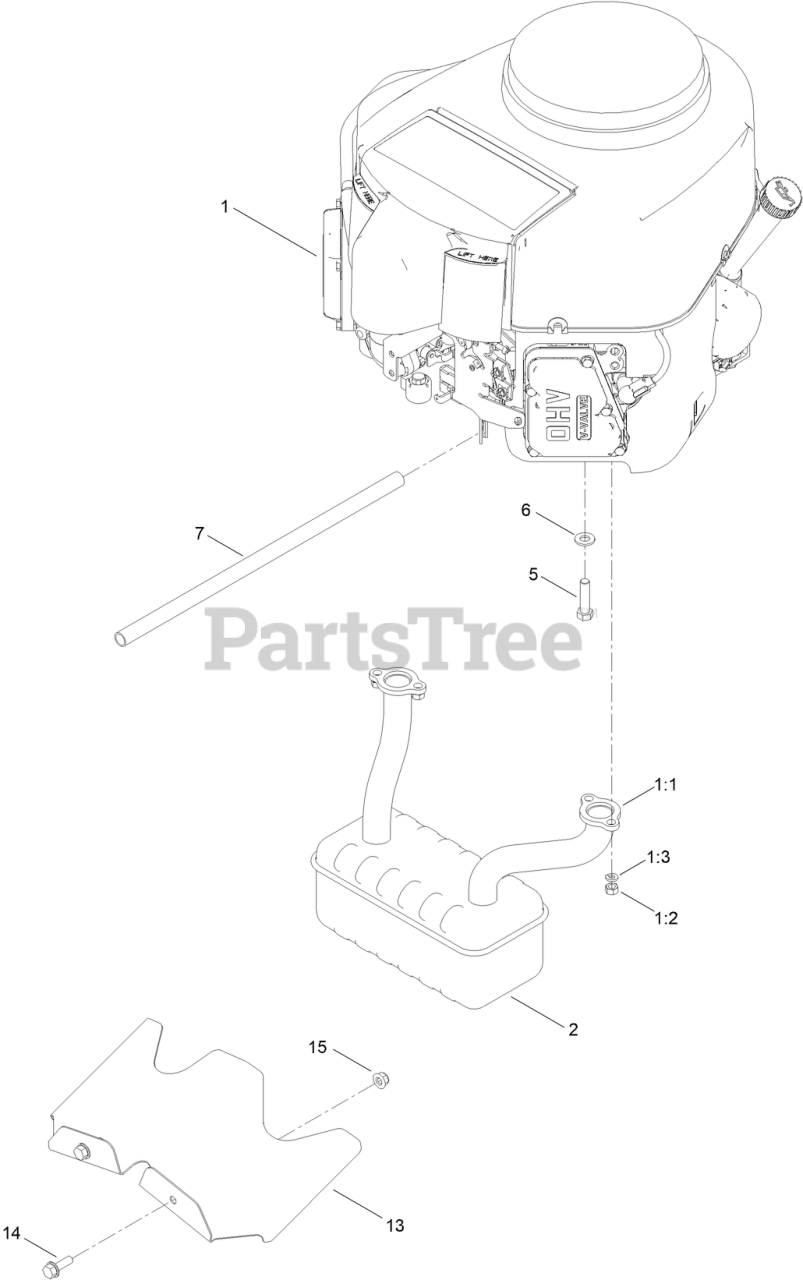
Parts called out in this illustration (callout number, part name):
1:1	GASKET-EXHAUST
1:3	WASHER-LOCK
2	MUFFLER
5	BOLT-HH
6	WASHER-FLAT
7	TUBE-DRAIN, OIL
13	SHIELD-HEAT
14	SCREW-HHF
15	NUT-HF, NI
